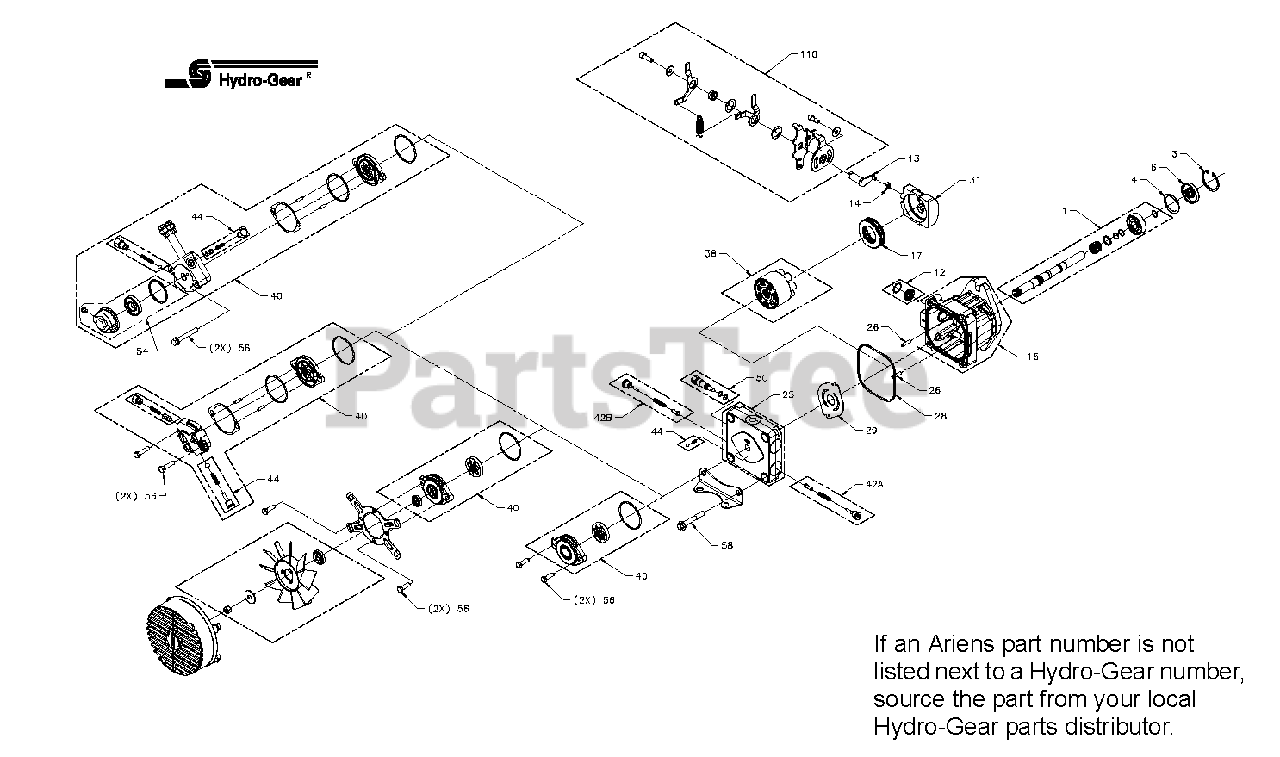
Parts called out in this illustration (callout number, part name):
1	Kit, Pump Shaft
3	Ring, Ret 47 Int
4	Washer, 1.45 x 1.84 x .04
6	Seal, Lip 17 x 47 x 8
12	Kit, BDP-16A Trunnion Seal
13	Arm, Trunnion
14	Guide, Slot
15	Service Kit, Housing
17	Bearing, Thrust Ball 42 x 68 x 16
25	Kit, End Cap
26	Pin, .219 x 1
28	O-Ring, Sq .1 x (4.3 x 4.6)
29	Valve Plate
31	Plate, Swash 21cc
38	Kit, Motor Block
40	Kit, Aux Pump
42	Kit, Shock Valve 200 Bar
44	Kit, Chrg Relief Valve
50	Kit, Bypass Valve
54	Auxilarty Filter Kit
56	HFHCS 5/16-18 x 2.5
58	Kit, Bolt
NS	Kit, Rtn
